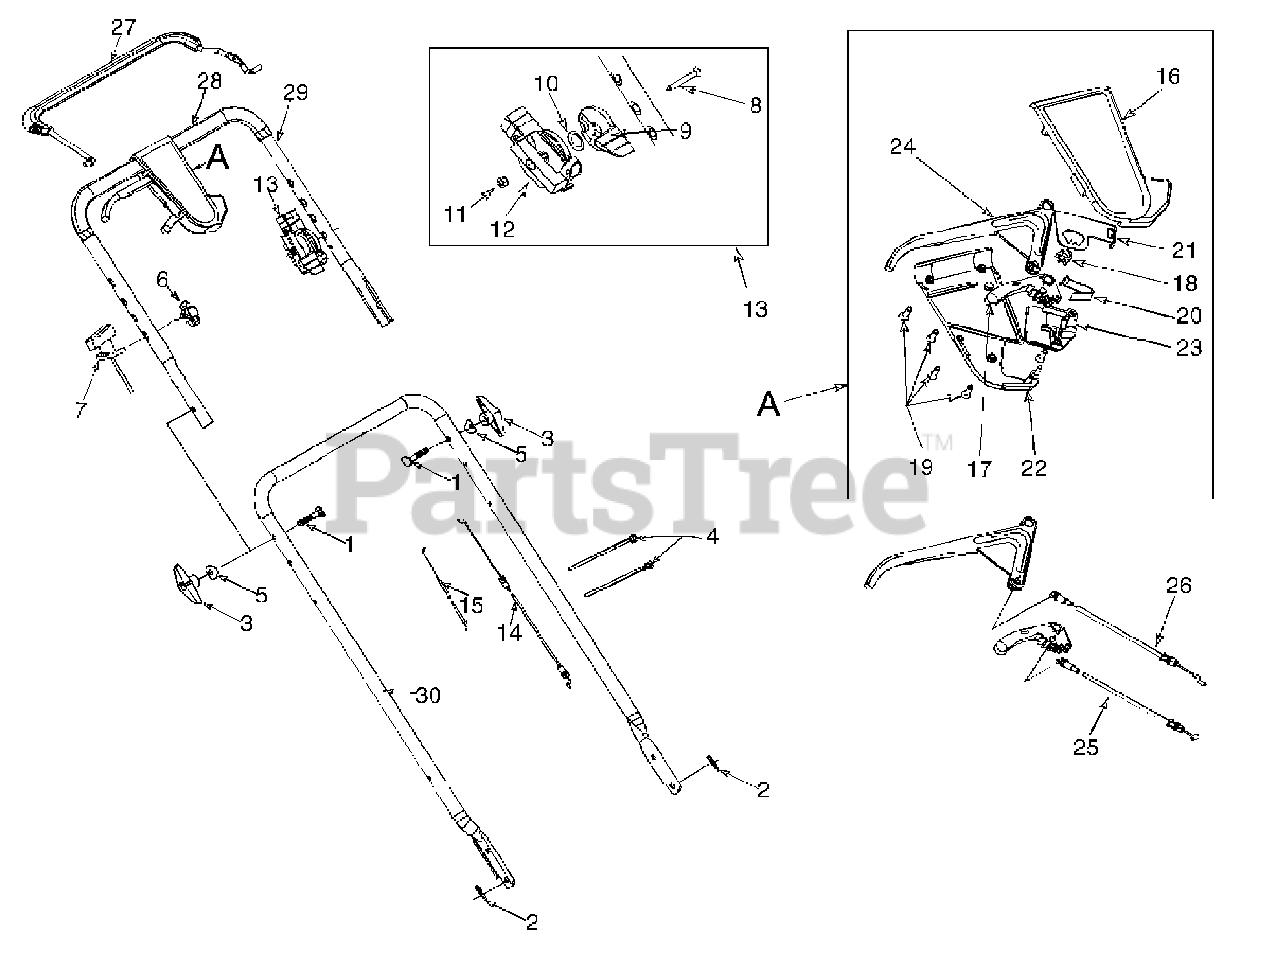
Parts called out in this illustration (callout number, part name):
1	Bolt Curv. Carr. 5/16-18 x 2.0
2	Cotter Pin .072 x 1.12 Lg.
3	Knob Assembly
4	Strap
5	Wash. Sad. .320 ID x .830 OD
6	Knob Handle ERS - 1/4-20
7	Rope Guide Eyebolt
8	Screw 1/4-20 x 1.81
9	Throttle Lever
10	Spring Wash. Curved
11	Nut 1/4-20 Top lock Nut Insert
12	Housing, Throttle
13	Throttle Control
14	Control Cable 47" Lg.
15	Cable, Throttle 60" Lg.
16	Upper Control Housing
17	6 Speed Shift Lever
18	Gear Insert
19	C Sunk Tap Scr #10 x .75 L
20	Shift Lever Spring
21	6 Spd. Rack Cable Brkt.
22	Lower Control Housing
23	Cable Mounting Cap
24	Control Lever
25	6 Spd. Cable
26	S.P. Cable
27	Control Handle
28	Foam Grip
